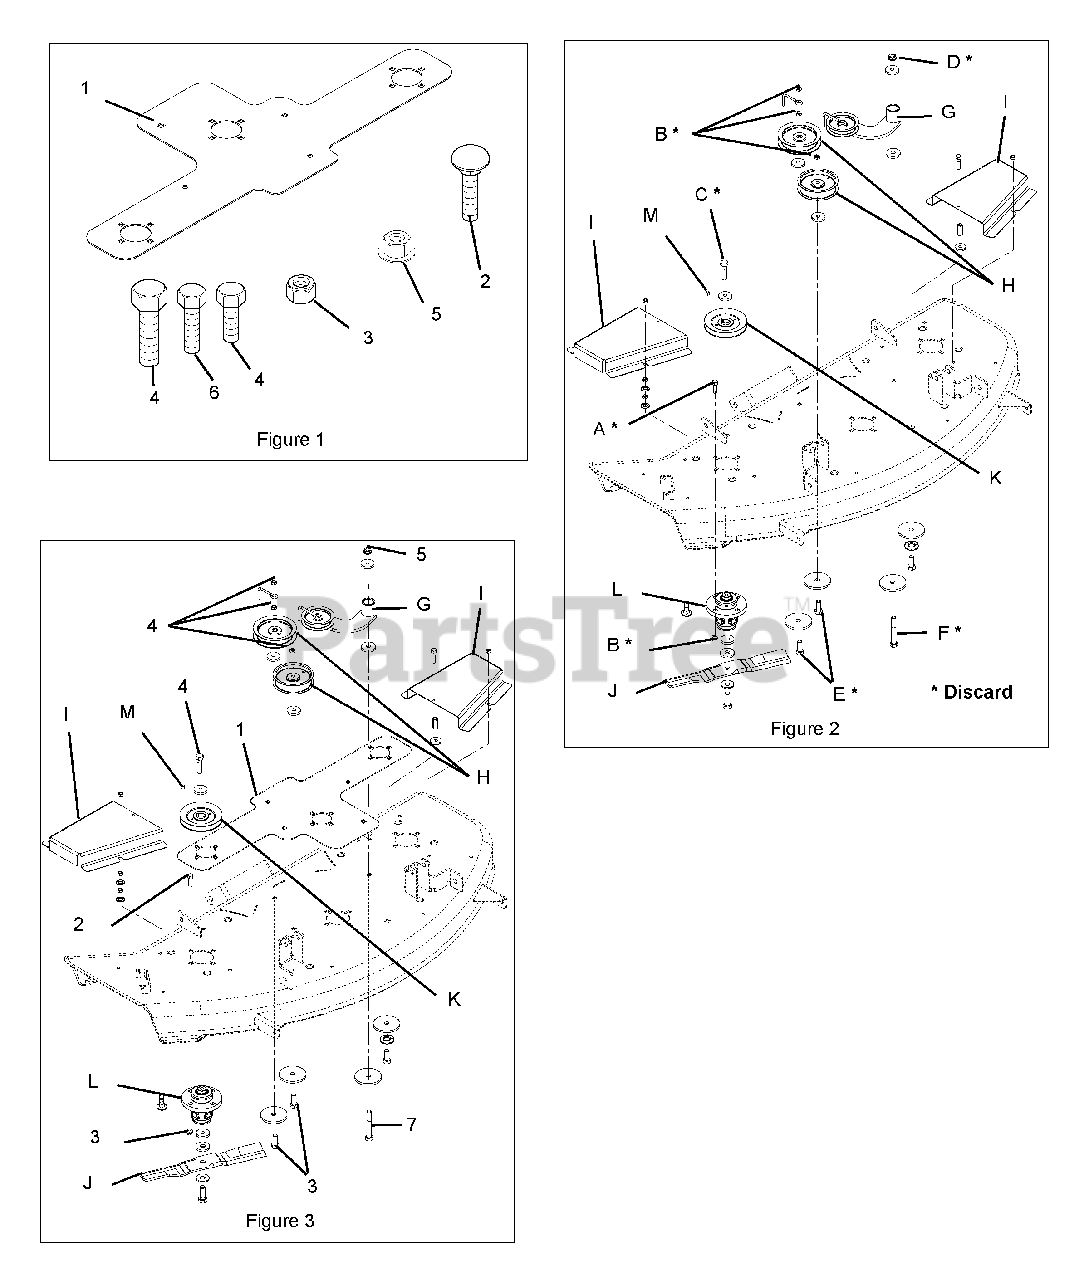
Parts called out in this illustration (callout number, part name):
1	50 DOUBLER PLATE, ZOOM
2	@BLT-RDHDSQNK .38-16X1.25 G5YZ
3	@NUT-LK-NYL-FLG .38-16 YWZC
4	BLT-HEX .38-16X1.0 GR8 YZ EP30
5	@NUT-LK-TOP-FLG .50-13 YWZC
6	@BLT-HEX .38-16X2.75 GR5 YWZC
7	@BLT-HEX .38-16X2.75 GR5 YWZC
A	3/8" x 1-1/4" Round Head Square Neck Bolt
B	3/8" Nylon Flange Nut
C	3/8" x 1" Hex Bolt
D	1/2" Top Lock Flange Nut
E	3/8" x 2-3/4" Hex Bolt
F	1/2" x 3-1/2" Hex Bolt
G	Idler Arm
H	Idler
I	Belt Cover
J	Mower Blade
K	Spindle Pulley
L	Spindle
M	Woodruff Key
